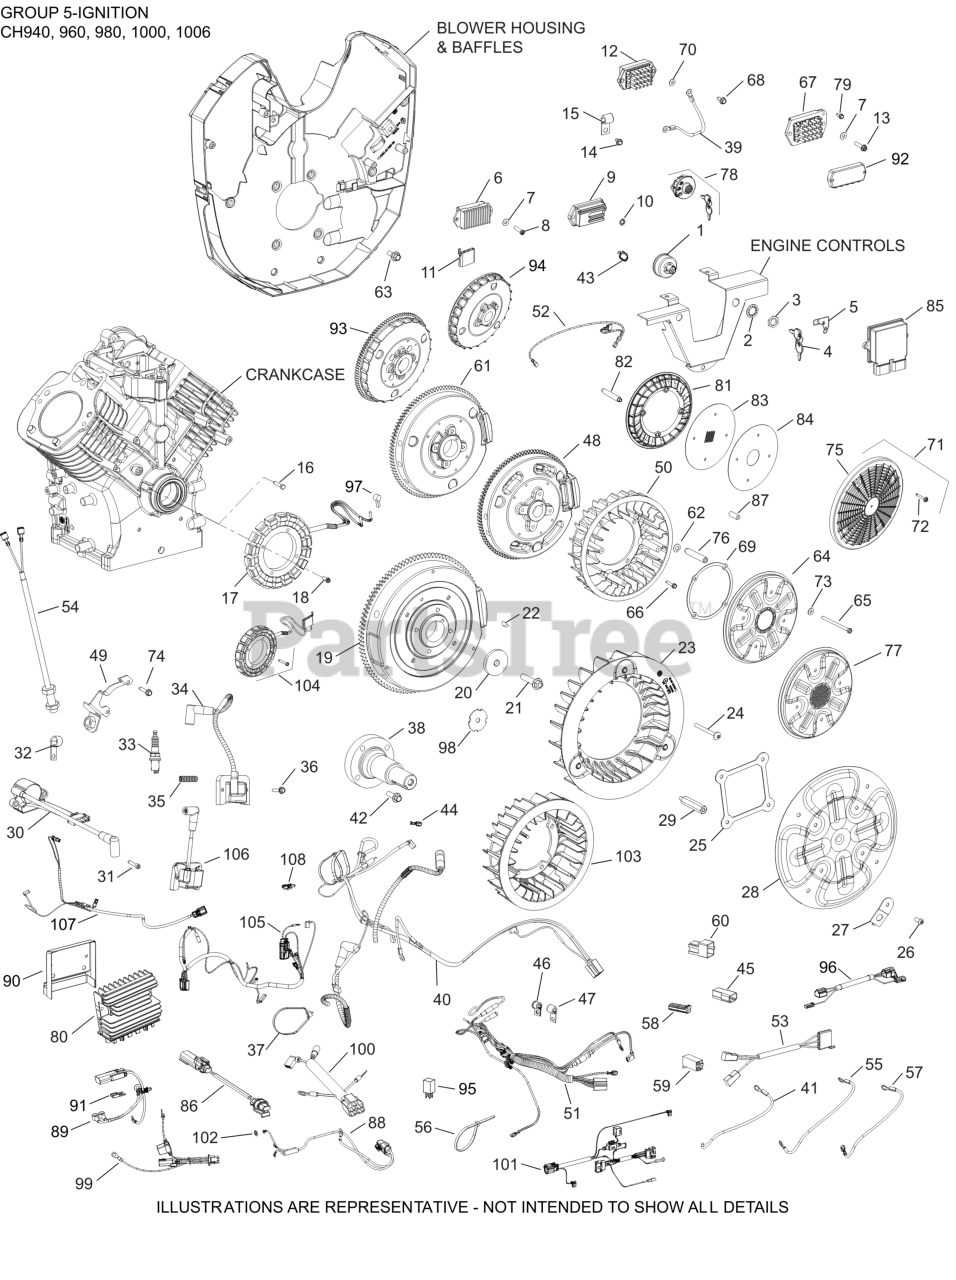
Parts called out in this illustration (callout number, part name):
20	WASHER, FLAT 13/32"
21	SCREW, HEX FLANGE
22	KEY, 3/16" X 5/8"
32	CLIP, CABLE
33	PLUG, SPARK
37	TIE, CABLE
61	FLYWHEEL, ASSEMBLY CARB
63	BOLT, SHOULDER
66	SCREW, THREAD THROWING
106	MODULE, DIGITAL IGNITION (LP/NG)
107	HARNESS, WIRING ASSEMBLY (DUAL TIMING)
108	TIE, WIRE
